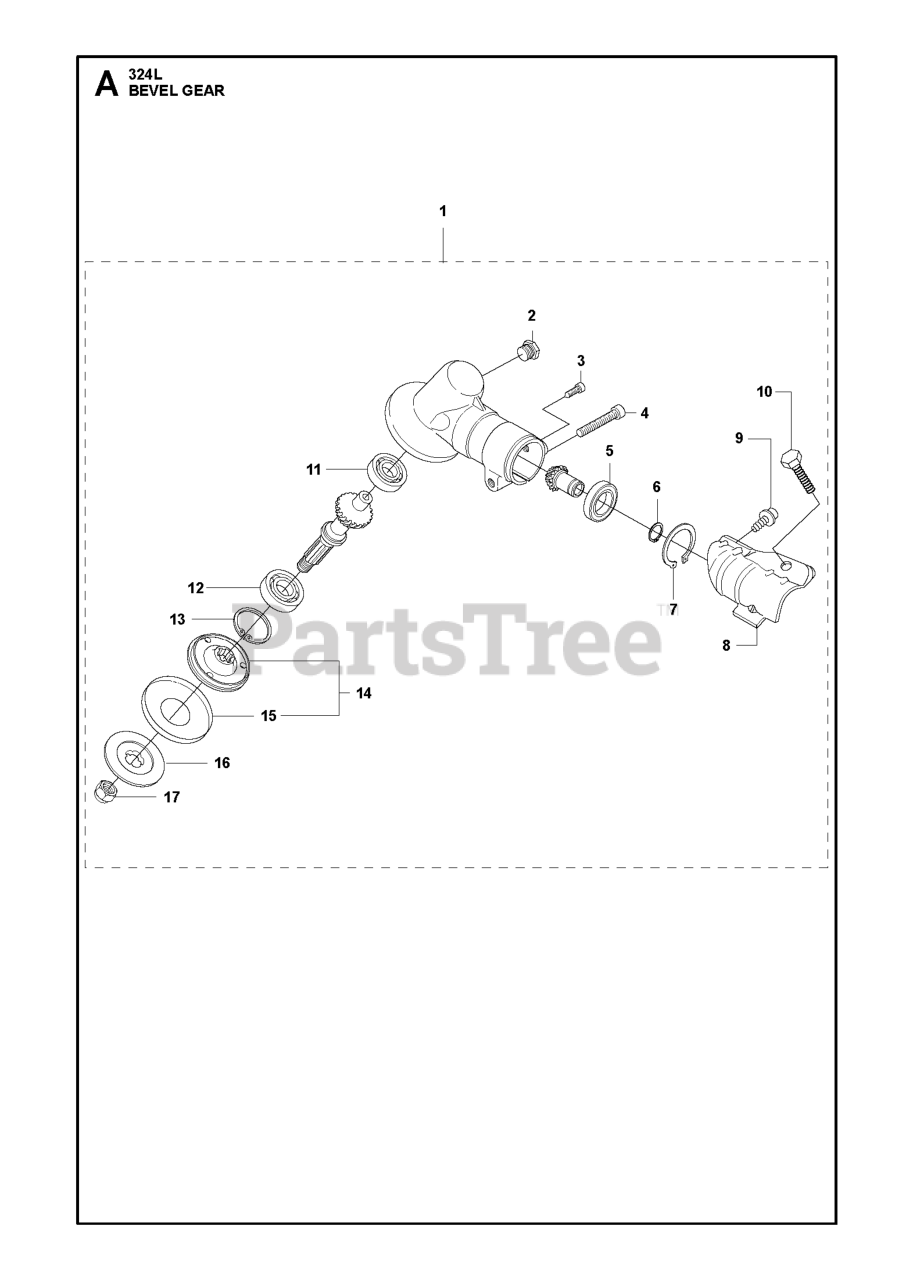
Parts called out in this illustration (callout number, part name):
1	ANGLE GEAR CPL 123L
5	BALL BEARING 24X9X1/609ZR
6	RETAINING RING
7	RETAINING RING
8	RP BRACKET TRIMMER GUARD
10	SCREW M6S 6X20
11	BALL BEARING 8X22X7/608Z
12	BEARING
13	RETAINING RING SGH 28
14	DRIVE DISC
15	WASHER
16	SUPPORT FLANGE
17	GEARHEAD NUT - BRUSHCUTTER
